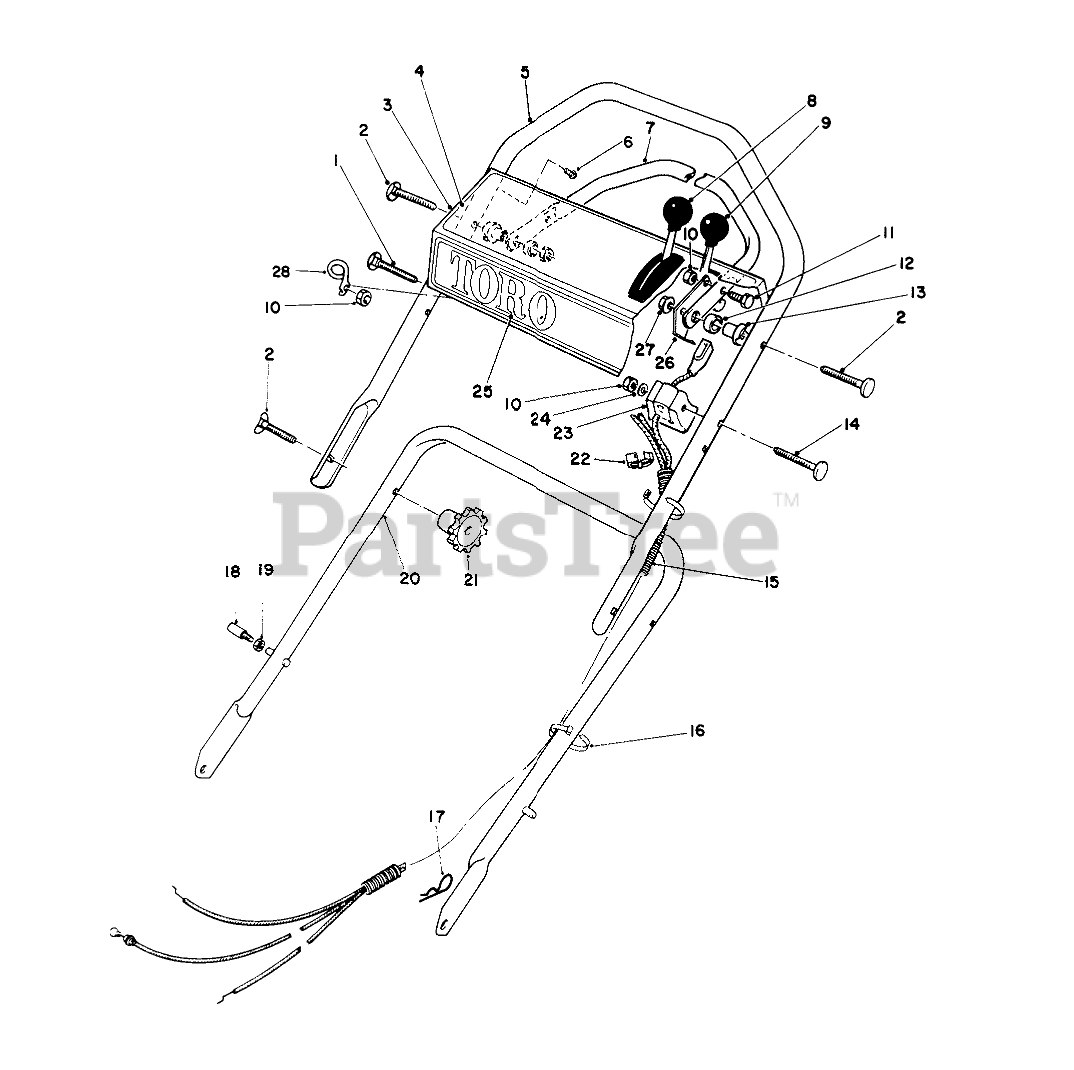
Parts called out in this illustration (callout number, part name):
1	HANDLE SCREW
2	5/16-18 X 2 HNDLE SCREW
3	Panel-Control (Incl. Ref. #4)
4	Decal-Instructions
5	Handle-Upper
6	SCREW-HWHTF
7	Bar-Control
8	SERVICE TRACT. CONTROL
9	THROTTLE CONT-SERVICE
10	NUT-LOCK, NI
11	SCREW-HH
12	SPACER-NYLON
13	SPACER-SUPPORT
14	HANDLE SCREW
15	CONT. CABLE COVER
16	TIE-CABLE
17	PIN-COTTER, HAIR
18	CHOKE DECAL
19	NUT-LOCK, NI
20	LOWER HANDLE ASM
22	FITTING-RING
23	SUPPORT-CABLE
24	WASHER-FLAT
25	Decal-Toro
26	Lever-Control
27	NUT-LOCK, NI
28	Guide
